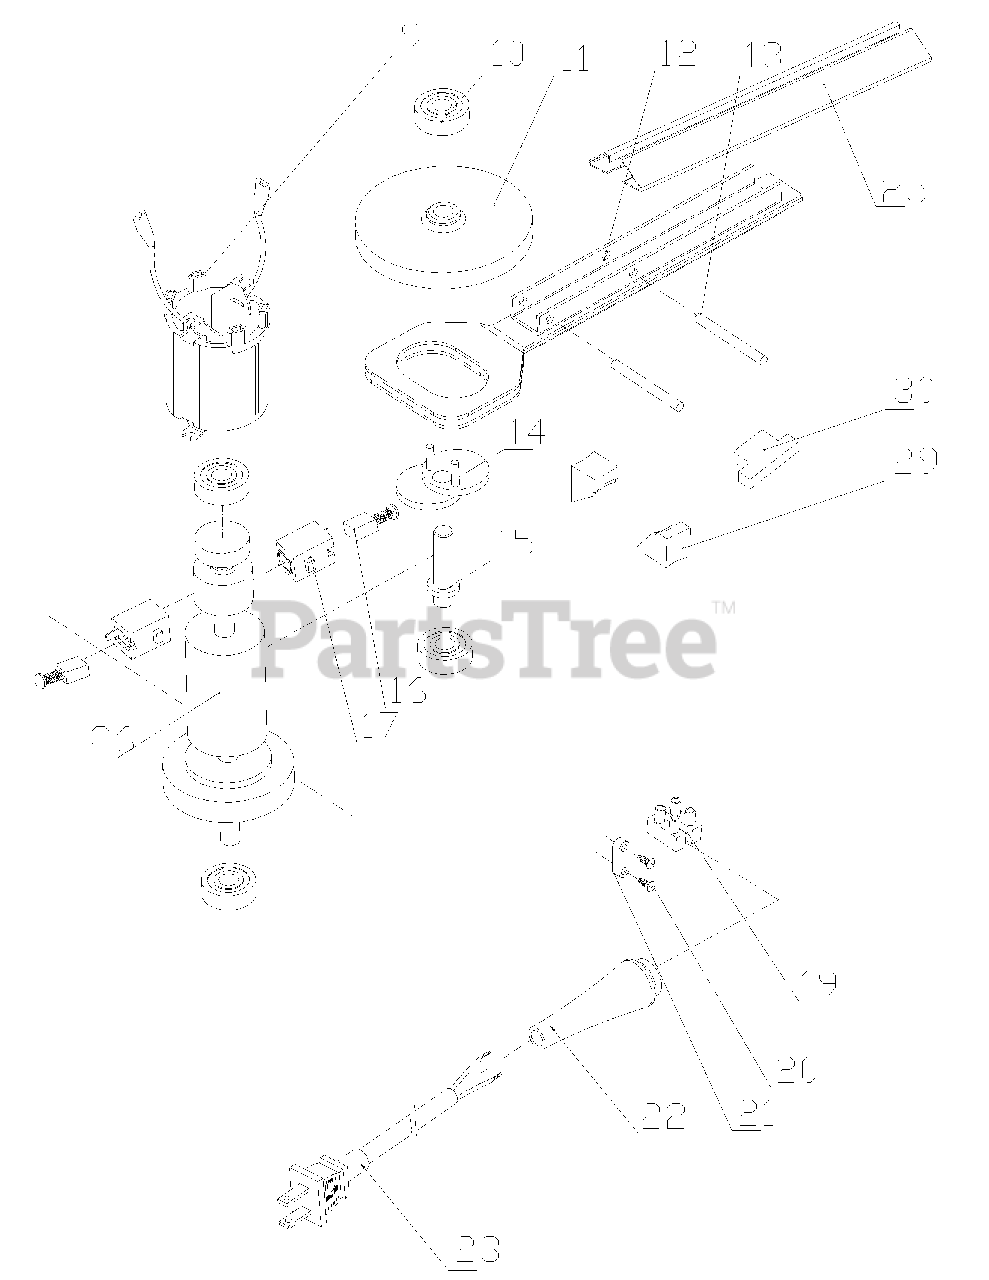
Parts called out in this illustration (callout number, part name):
7	HOUSING (L)
9	FIELD ASS'Y
12	20" BLADE
14	ECCENTRIC SHAFT
15	OUTPUT SHAFT
17	BRUSH HOLDER
18	HOUSING (R)
19	TERMINAL BLOCK
21	STRAIN RELIEF
22	CORD GUARD
23	POWER CORD
25	BLADE COVER
31	LABEL (R)
32	LABEL (L)
